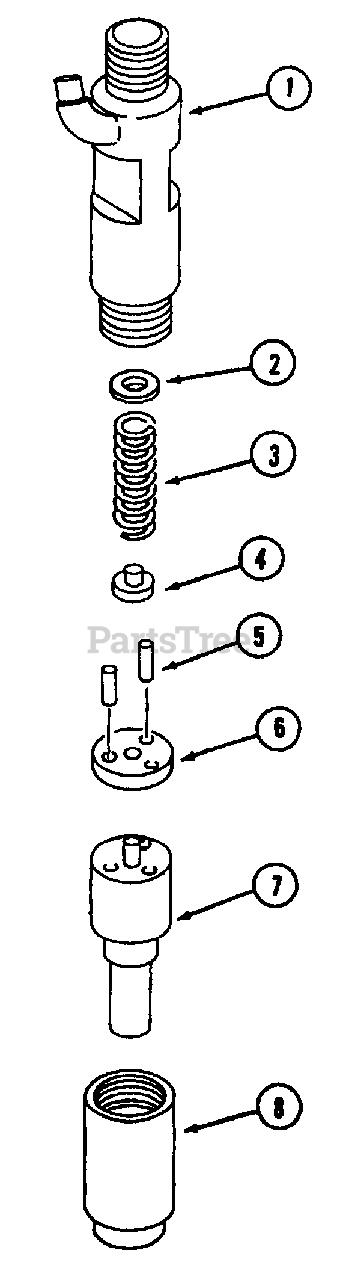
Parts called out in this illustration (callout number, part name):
1	Body Sub Ass'y.
2	Washer T=1.00
3	Spring, Pressure
4	Pin, Pressure
5	Pin, Straight
7	Nozzle Ass'y.
8	Nut, Nozzle Retaining
